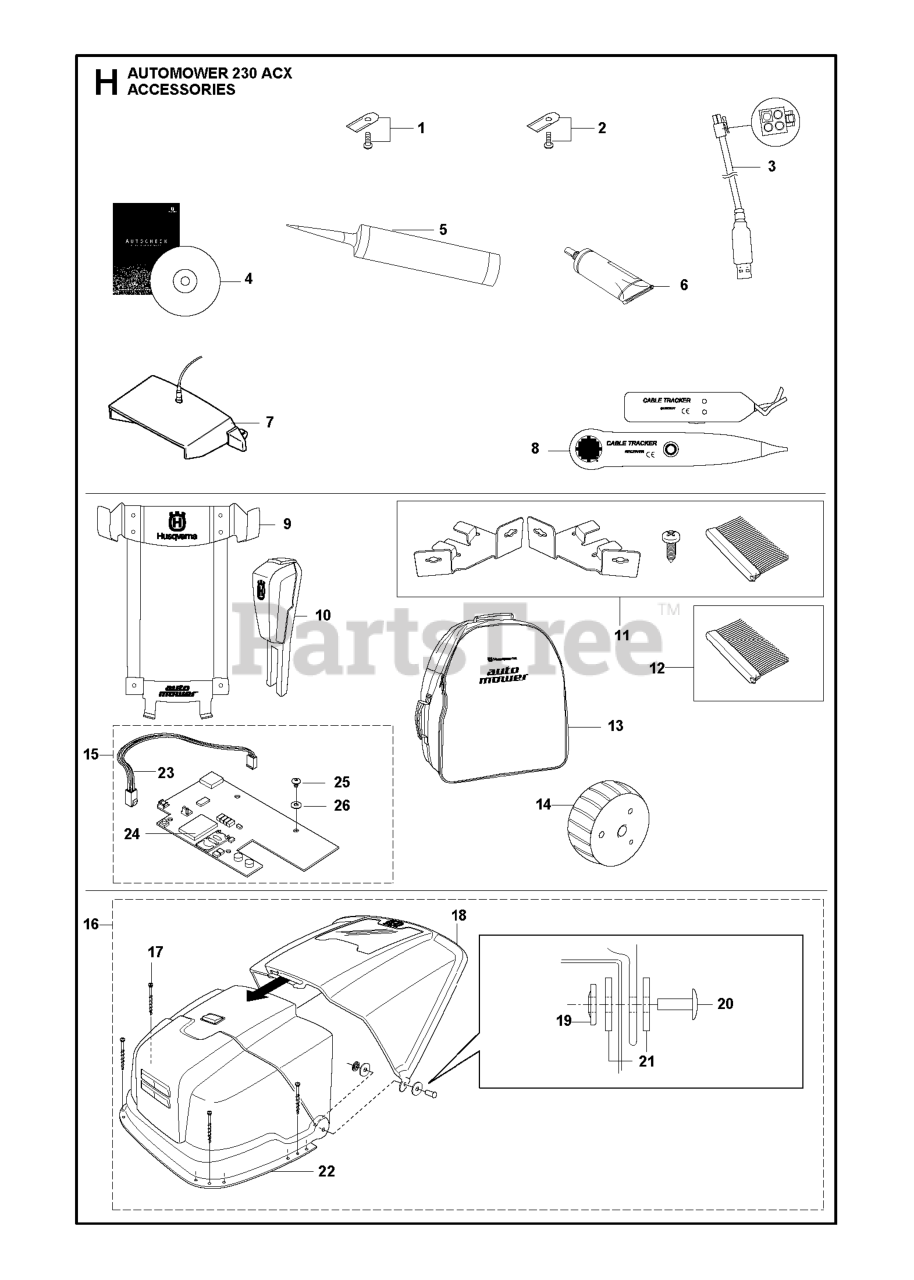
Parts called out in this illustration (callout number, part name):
1	HUS 9 PC BLADE SET .35MM
1	BLADE KIT
1	BLADE - BULK PACK 500 PCS
1	BLADE 45PCS, CARBON
2	BLADE 9 PCS EXTRA THICK
2	BLADE
2	BLADE 300PCS -SINGLE HOLE THIC
2	BLADE BLADE KIT INCL PACKAGING
3	USB SERVICE CABLE
5	GREASE 300 ML
6	SEALANT
6	GREASE OKS 110 85ML
7	N/A PIN CODE TRANSFER UNIT ADA
8	TEST EQUIPMENT
9	WALL BRACKET ASSY
10	SIGNAL BOOSTER
11	BRUSH KIT
11	BRUSH KIT BRUSH X6, HOLDER X2,
12	BRUSH KIT
14	HEAVY FRONT WHEEL KIT INCL PAC
14	WHEEL ASSY
16	AUTOMOWER SHELTER
17	SCREW KIT CS
18	TOP INCL LOGO & WINDOW CHARG
19	LOCK WASHER
20	AXLE CHARGING STATION COVER
22	FRONT CHARGING STATION COVER
23	LOOM LOOM GPS TRACKING MODULE
24	BATTERY GPS TRACKING COMMUNICA
25	SCREW GSM- MODULE
26	WASHER GSM- MODULE
